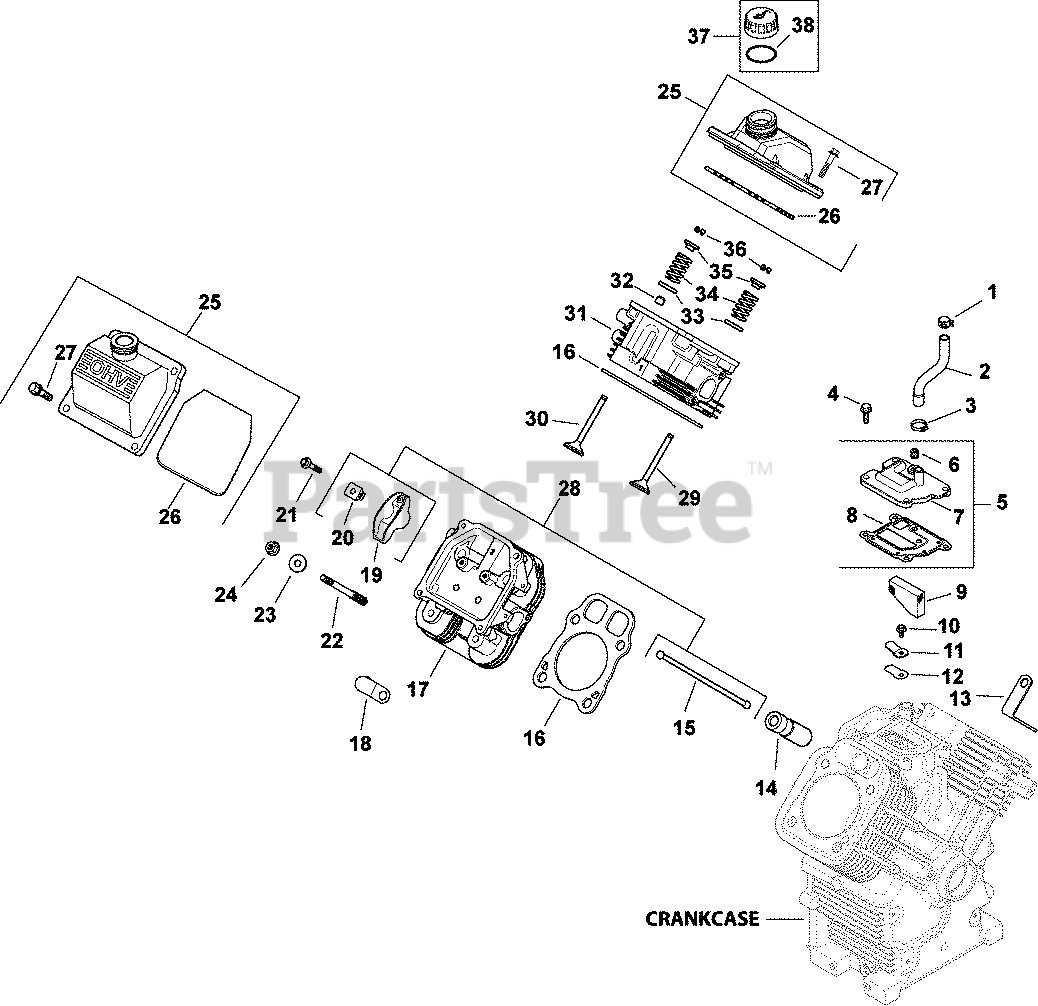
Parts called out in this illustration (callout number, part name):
1	CLAMP, BAND SPRING HOSE-(#2523737S)
2	HOSE, BREATHER-USE 24 326 89-S
3	CLAMP, HOSE (KM)-USE 25 237 31-S
4	SCREW,FLG THD FRM M6X1.0X20-(#25086396S)
5	KIT, BREATHER ASSEMBLY
6	PLUG, CTSK PIPE 1/8"
7	COVER, BREATHER -USE 24 033 01-S
8	GASKET, BREATHER-USE 24 041 67-S
9	FILTER, BREATHER-USE 24 050 11-S
10	SCREW, FLG THD FRM M5X.8X10
11	RETAINER, REED
12	REED, BREATHER
13	STRAP, LIFTING-USE 25 445 03-S
14	LIFTER, HYDRAULIC VALVE-USE 25 351 10-S
15	ROD, PUSH
16	CYL HEAD GASKET KIT-USE 24 841 04-S
17	KIT, CYLINDER HEAD #2 USE 24 318 149-S
18	KIT, HI TEMP CUTOUT SENSOR
19	ARM, ROCKER
20	PIVOT, ROCKER ARM
21	SCREW, FLG M6X1.0X34
22	STUD, M8X1.25
23	WASHER, FLAT 8.6 MM
24	NUT, FLG M8X1.25
25	KIT, VALVE COVER-OIL FILL
26	O-RING (YELLOW), VALVE COVER
27	SCREW, FLG M6X1.0X30
28	KIT, VALVE TRAIN
29	VALVE, INTAKE (STD)
30	VALVE, EXHAUST (STD) - USE 32 016 01-S
31	KIT, CYLINDER HEAD #1 - (#24318143S)
32	SEAL, VALVE STEM - (#2503214S)
33	RETAINER, SPRING
34	SPRING, VALVE
35	CAP, VALVE SPRING
36	KIT, RETAINER
37	KIT, OIL FILL CAP (YELLOW)
38	O-RING, DIPSTICK
2401602-S	VALVE, EXHAUST (.25)
2401702-S	VALVE, INTAKE (.25)
